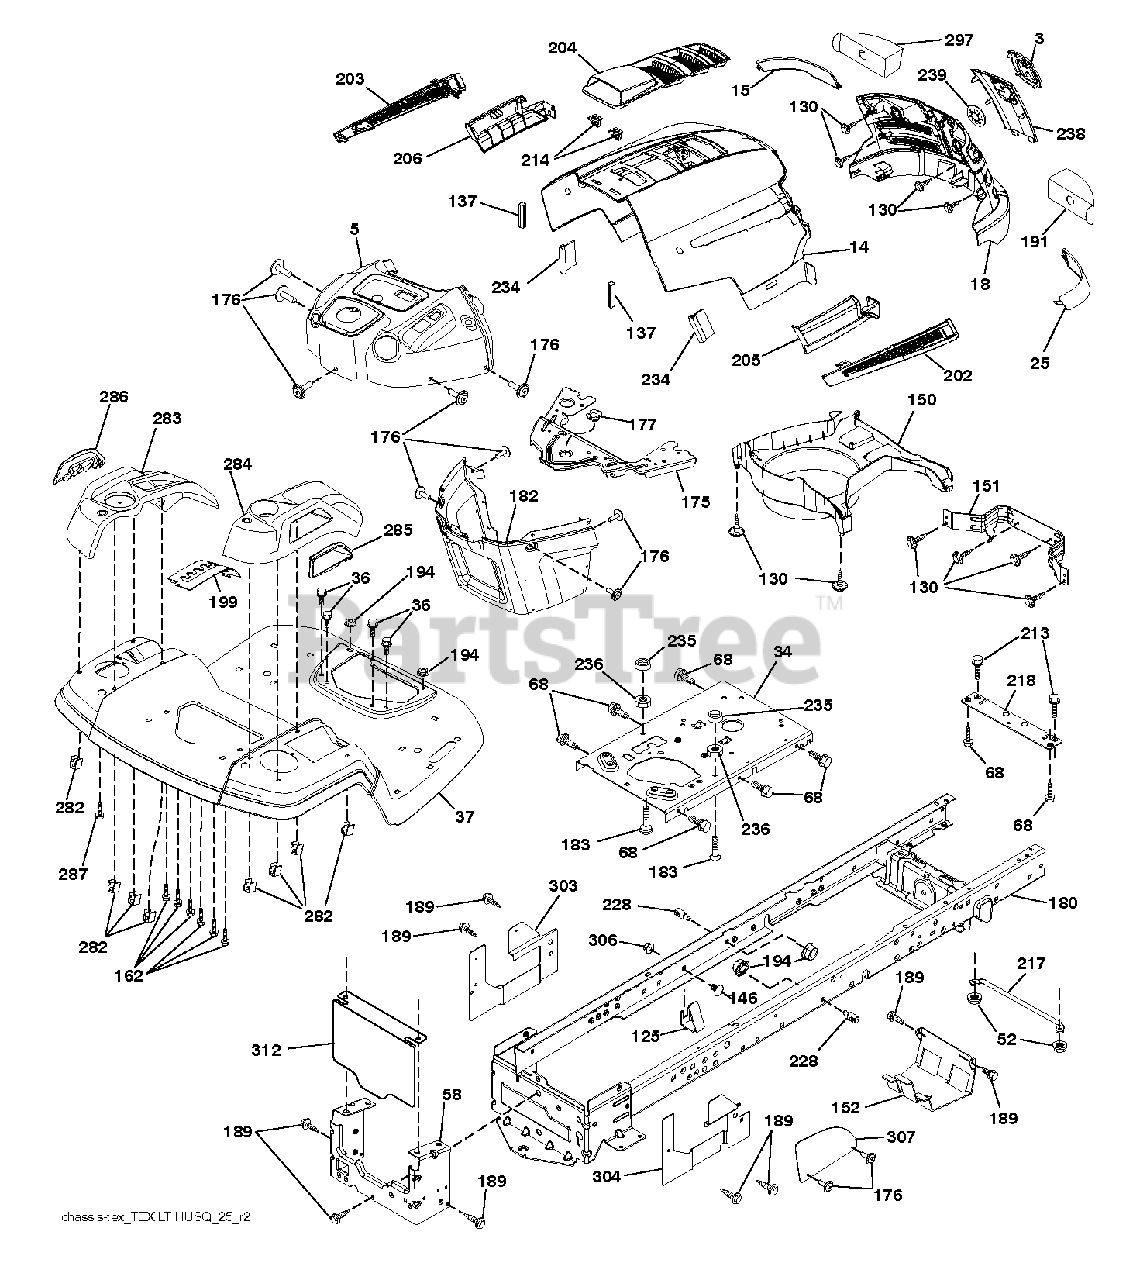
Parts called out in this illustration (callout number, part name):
3	LOGO.HUSQ.GT.LT.CROWN.H
5	SUBASM.DASH.UPPER.HLT.498
14	HOOD
15	LENS.HUSQVARNA LT.RH
18	GRILLE.SVC.HUSQVARNA.GREY
25	LENS.HUSQVARNA LT.RH
34	PLATE.ENGINE.WELDED.CHASSIS
36	SCREW 5/16"
37	FENDER.TLT.FS.W/NO CUPHLD.667
52	LOCKNUT
58	DRAWBAR UPPER 2PC SMALL FENDER
68	SCREW LT
125	CLIP.FUEL.LINE
130	SCREW.#10 X 0.750.BOS
137	BUMPER DASH
146	BOLT.RDHD.SHT.SQNK.3/8-16X5/8
151	BRACKET PIVOT
152	SHIELD.BROWNING.W/TEX
162	SCREW.HI-LO.CONSOLE
175	CROSSMEMBER
176	SCREW.#10-24X5/8.RN.QU
177	BUSHING STEERING
180	CHASSIS.WLDMNT.14GA.2PC.18".TI
182	DASH.LOWER.PREDATOR LT
183	BOLT.5/16-18X1-1/4 FULL THD
189	SCREW
191	INSERT.REFLECTIVE.RH.
194	NUT LOCK HEX FLANGE 5/16-18
199	PLATE.DECK.LIFT.HUSQ.LT
202	VENT.SIDE.HUSQVARNA.LT.RT
203	VENT.SIDE.HUSQVARNA.LT.LFT
204	SUBASM.TOP.VENT.HUSQ.LT
205	SKIRT.SIDE.HUSQVARNA.LT.RT
206	SKIRT.SIDE.HUSQVARNA.LT.LEFT
213	BOLT
214	CLIP.RETAINER.TINNER.
217	ROD.PIVOT.HOOD
218	X-PIECE.HOOD.STOP.NON/
228	STUD.FASTNER.W/ANTI-ROTATE
234	BUMPER.HOOD.TEX.HUSQVARNA
235	SPACER FENDER
236	NUT.CENTERLOCK.5/16-
238	TRIM.HUSQ LT.668
282	CLIP.RETAINER.CONSOLE.LT.HUSQ
283	CONSOLE.ASM.LFT.RSF.HUSQ.LT
284	CONCOLE.CNTRL.PDL.HUSQ.LT.498
285	CONSOLE INSERT RH
286	CONSOLE.INSRT.LH.HUSQ.LT.BLACK
287	SCREW 1/4X20
297	INSERT REFLECTIVE
303	SHIELD CHASSIS LEFT
306	NUT LOCK FLG 3/8-16 UNC
307	SHIELD UPPER PEDAL
312	SHIELD.PNT.DRAWBAR.FRENCH
